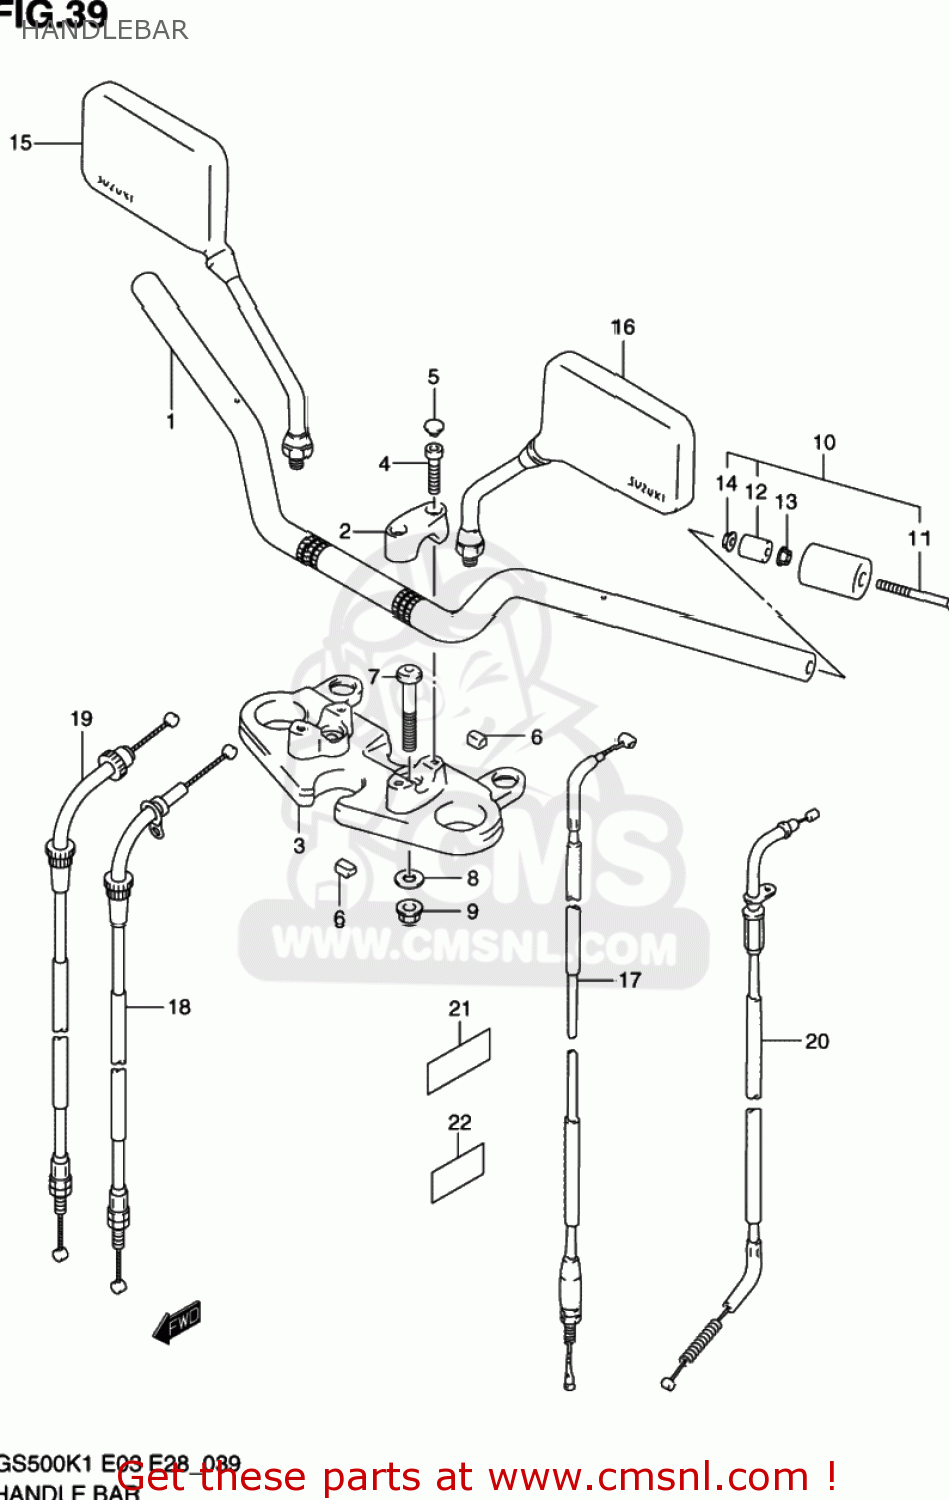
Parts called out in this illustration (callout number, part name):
1	HANDLEBAR
2	CLAMP,HANDLEBAR UPR
3	HOLDER,HANDLEBAR LWR
4	BOLT
5	CAP(OD:11)
6	CUSHION,HANDLE HOLDER
7	BOLT
8	WASHER(10.5X30X3.2)
9	NUT
10	BALANCER SET,H
11	SCREW,HANDLE B
12	EXPANDER,HANDLE BALANCER
13	NUT
14	NUT
15	MIRROR ASSEMBLY,REAR VIEW
16	MIRROR ASSEMBLY,REAR VIEW
17	CABLE ASSY,CLUTCH
18	CABLE ASSY,THROTTLE NO.1
19	CABLE ASSY,THROTTLE NO.2
20	CABLE,STARTER
21	PROTECTOR
22	TAPE,SIDE GATE PROTECTION FR
